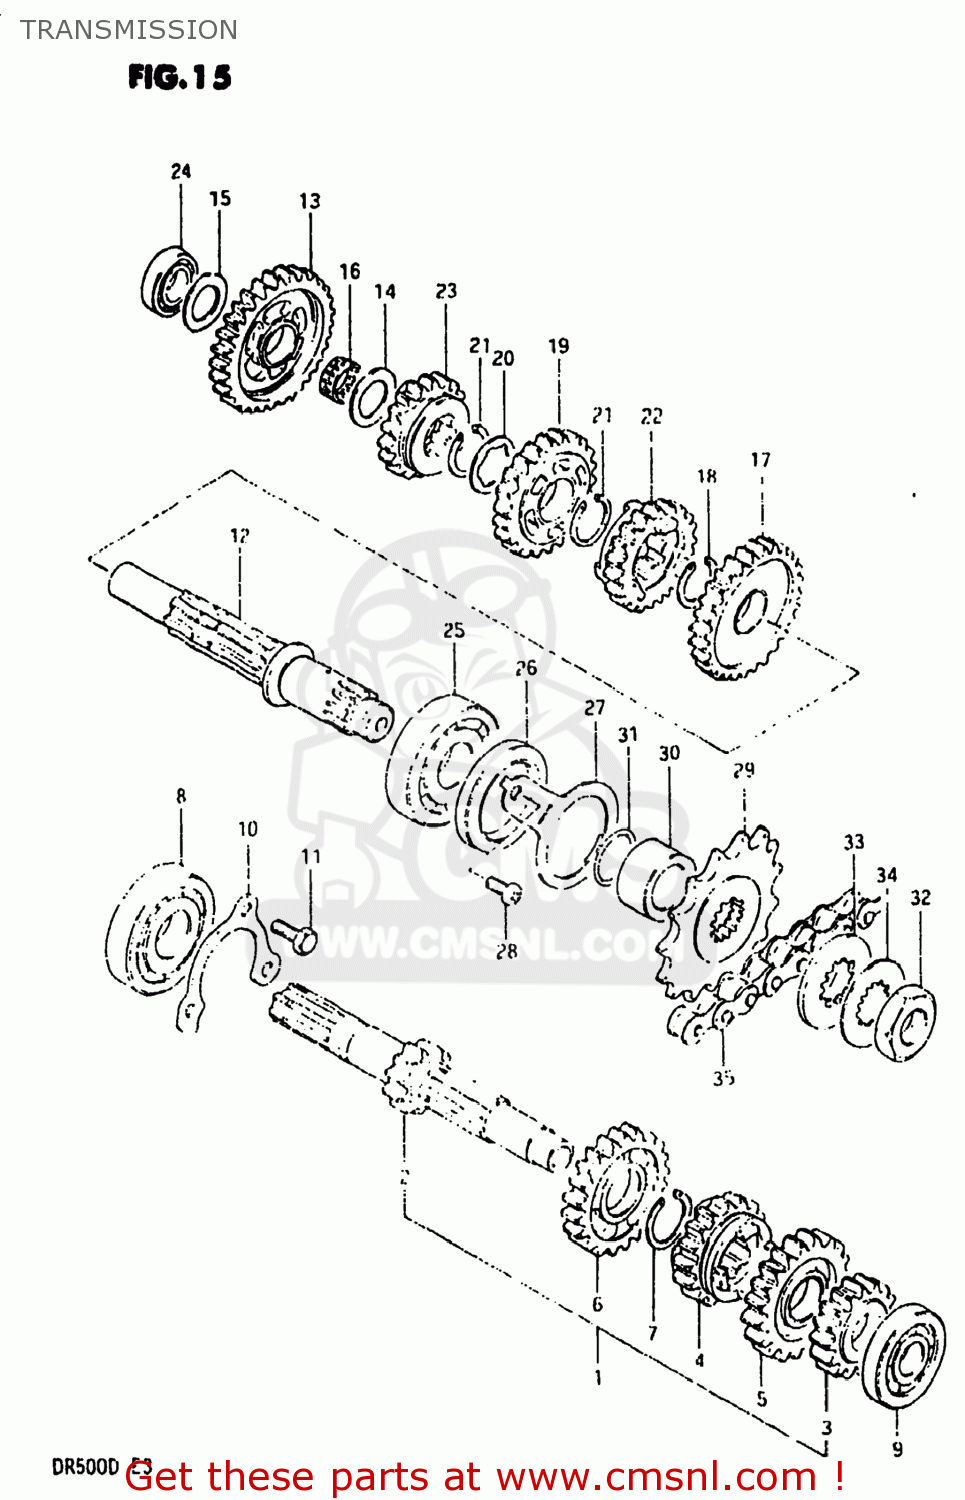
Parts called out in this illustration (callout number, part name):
1	SHAFT,COUNTER
2	SHAFT,COUNTER
3	GEAR,SECOND DRIVE
4	GEAR,THIRD DRIVE
5	GEAR,FOURTH DRIVE
6	GEAR,FIFTH DRIVE
7	CIRCLIP
8	BEARING
9	BEARING
10	PLATE,COUNTERSHAFT BEARING
11	BOLT
12	SHAFT,DRIVE
13	GEAR,FIRST DRIVEN
14	WASHER
15	WASHER
16	BEARING(20X24X10).8
17	GEAR,SECOND DRIVEN
18	CIRCLIP
19	GEAR,THIRD DRIVEN
20	WASHER,LOCK
21	CIRCLIP
22	GEAR,FOURTH DRIVEN
23	GEAR,FIFTH DRIVEN
24	BEARING(20X42X12)
25	BEARING
26	SEAL,OIL(32X42X7)
27	PLATE,DRIVESHAFT OIL
28	BOLT
29	SPROCKET,ENGINE (NT:14)
30	SPACER (22X32X13.4)
31	O RING(D:1.7,ID:22)
32	NUT
33	SPACER,ENGINE SPROCKET
34	WASHER,LOCK
35	CHAIN ASSEMBLY,DRIVE
